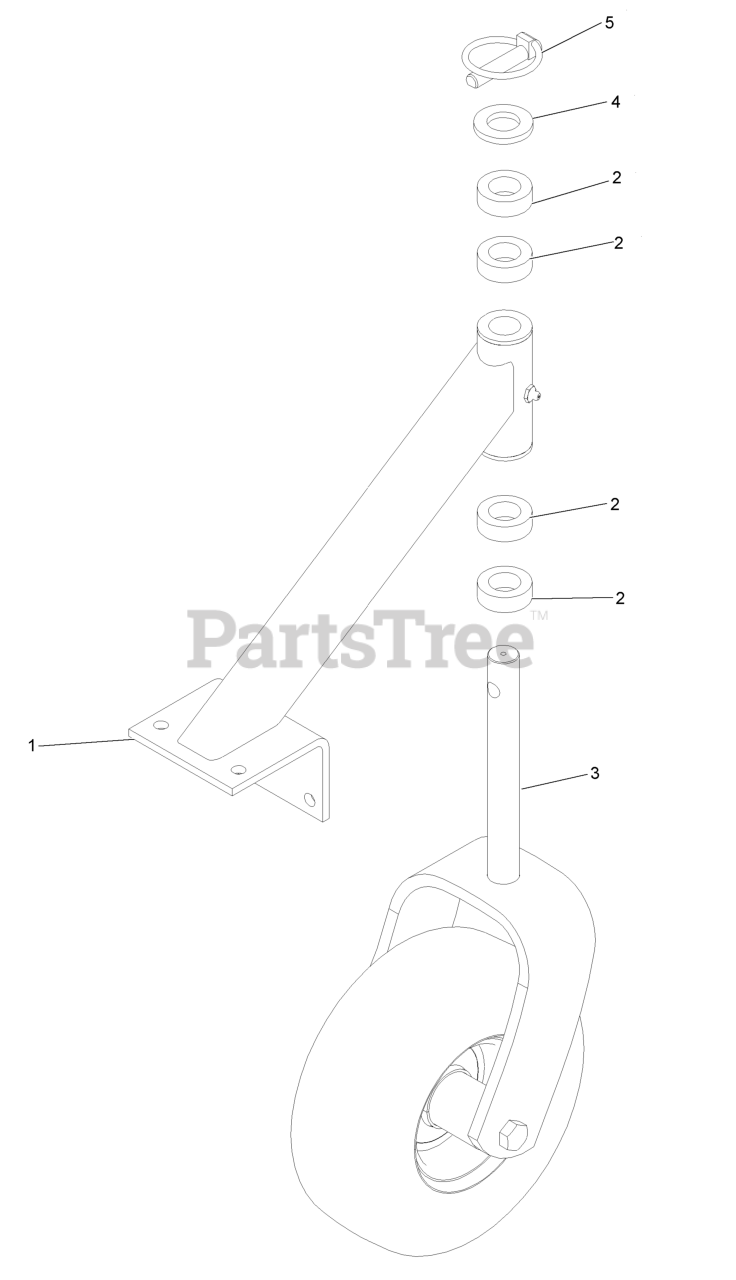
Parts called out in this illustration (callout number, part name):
1	ASM,CSTR SUPPORT W/WEIGHT
2	SPACER-CASTER
3	ASM,CASTER/WHEEL
4	WASHER-FLAT
